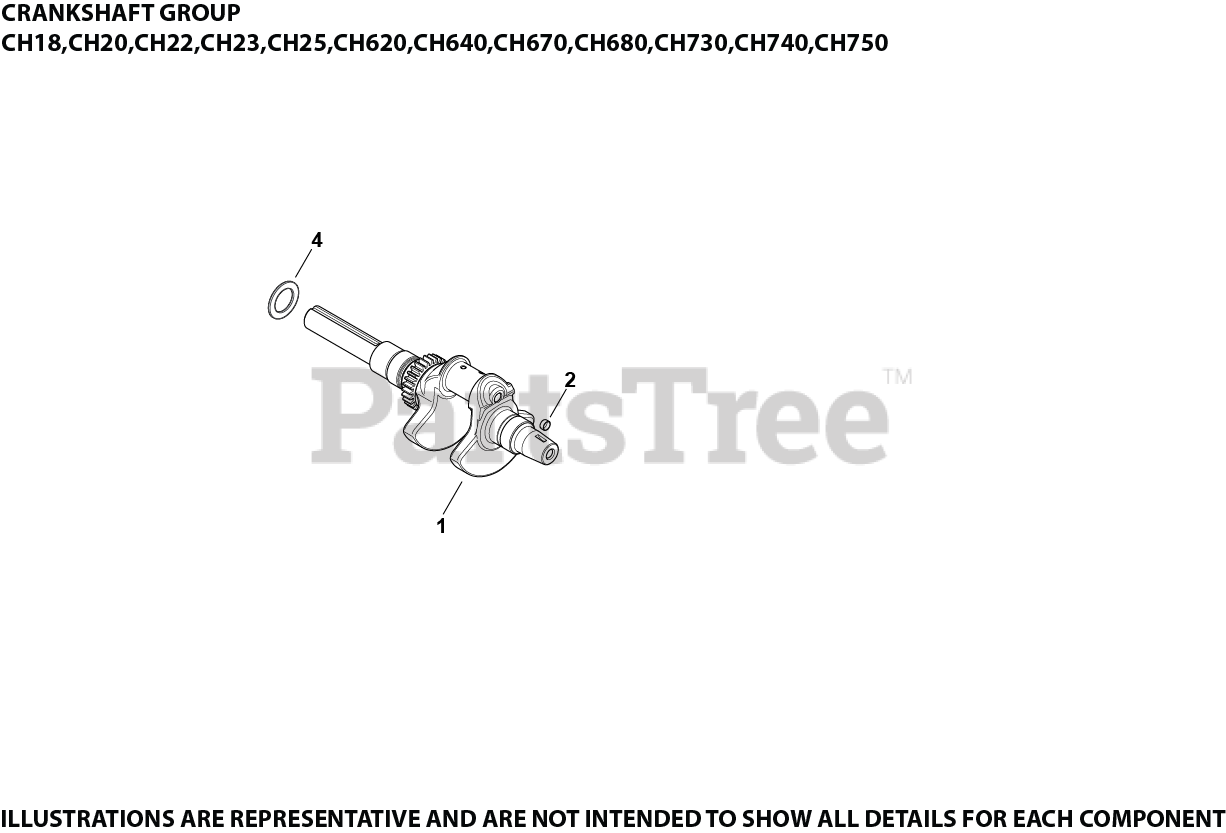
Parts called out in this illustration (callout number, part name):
1	CRANKSHAFT, THRUST STYLE
2	PLUG, CUP
4	SHIM, THRUST (GREEN .875MM) - DISCONTINUED
4	SHIM, THRUST (BLUE .5MM)
4	SHIM, THRUST (BLACK .686MM)
